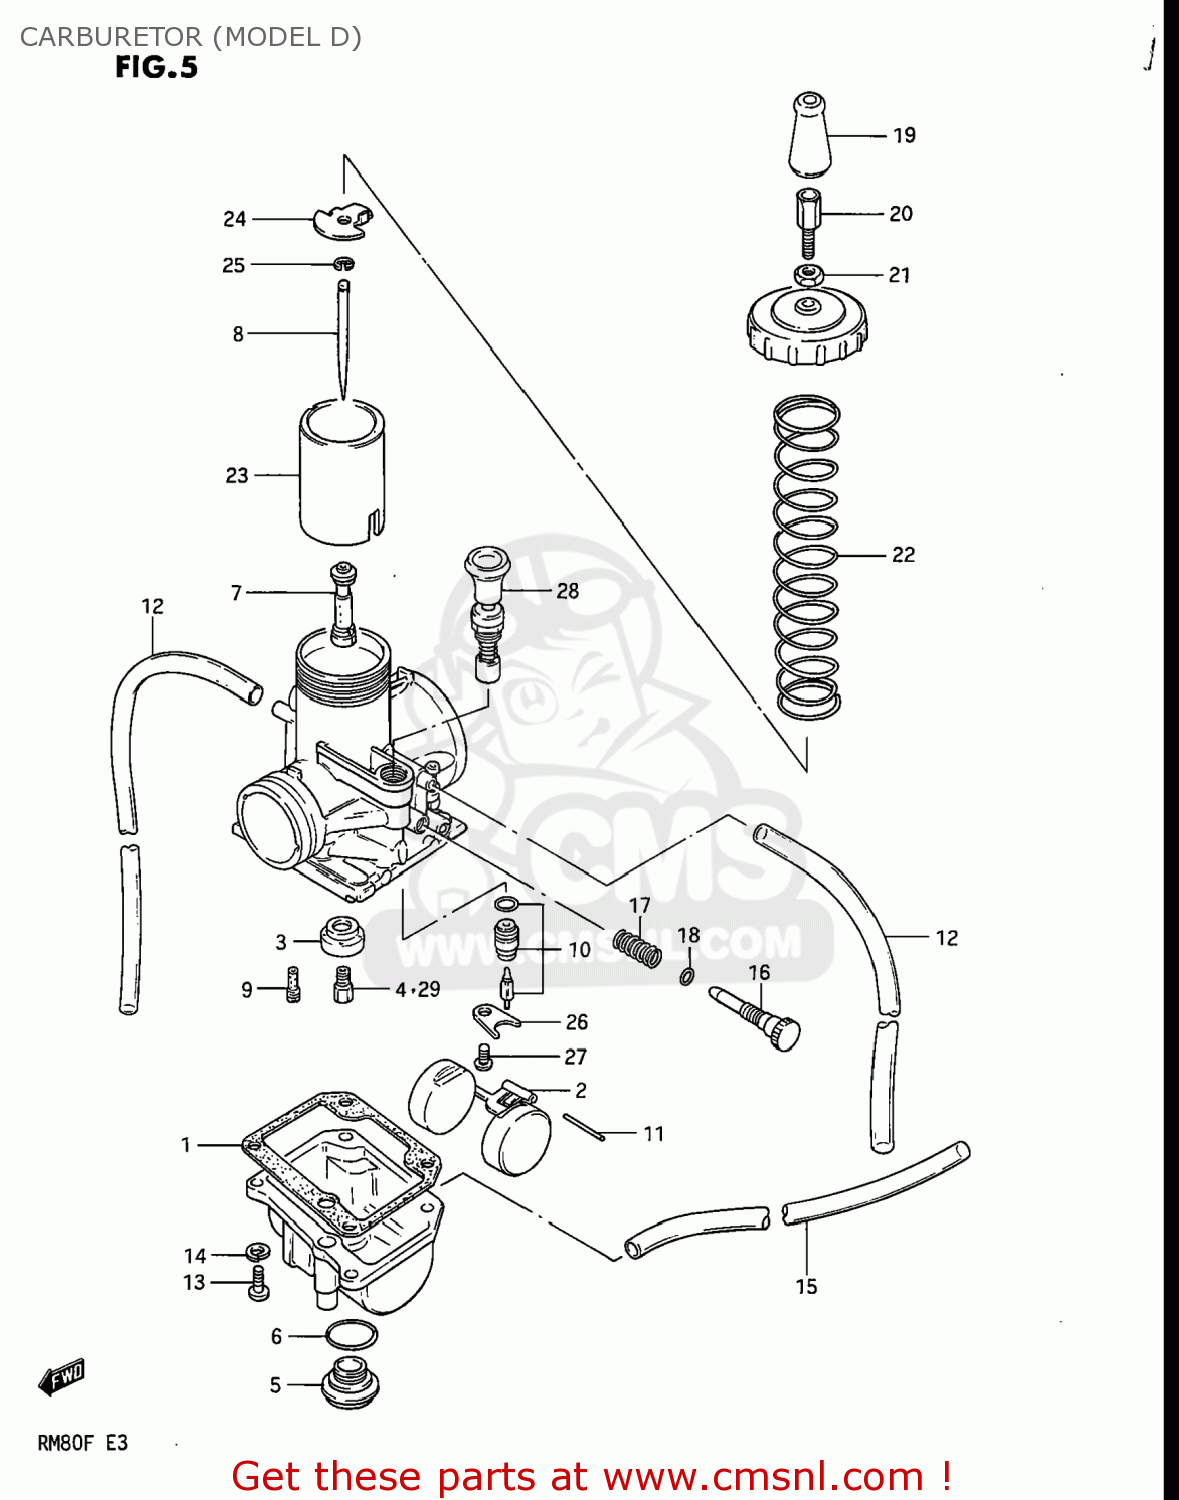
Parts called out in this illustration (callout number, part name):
1	GASKET,FLOAT CHAMBER (NAS)
2	FLOAT
3	RING
4	JET
5	PLUG
6	O RING
7	JET,NEEDLE
8	NEEDLE,JET
9	JET
10	VALVE ASSEMBLY,NEEDLE
11	PIN,FLOAT
12	HOSE
13	SCREW
14	LOCK WASHER
15	HOSE
16	ADJUSTER
17	SPRING
18	O RING
19	CAP,RUBBER
20	ADJUSTER,CABLE
21	NUT
22	SPRING,THROTTLE VALVE
23	VALVE,THROTTLE
24	PLATE,THROTTLE VALVE
25	CLIP
26	PLATE
27	SCREW
28	VALVE ASSEMBLY,STARTER
29	JET
